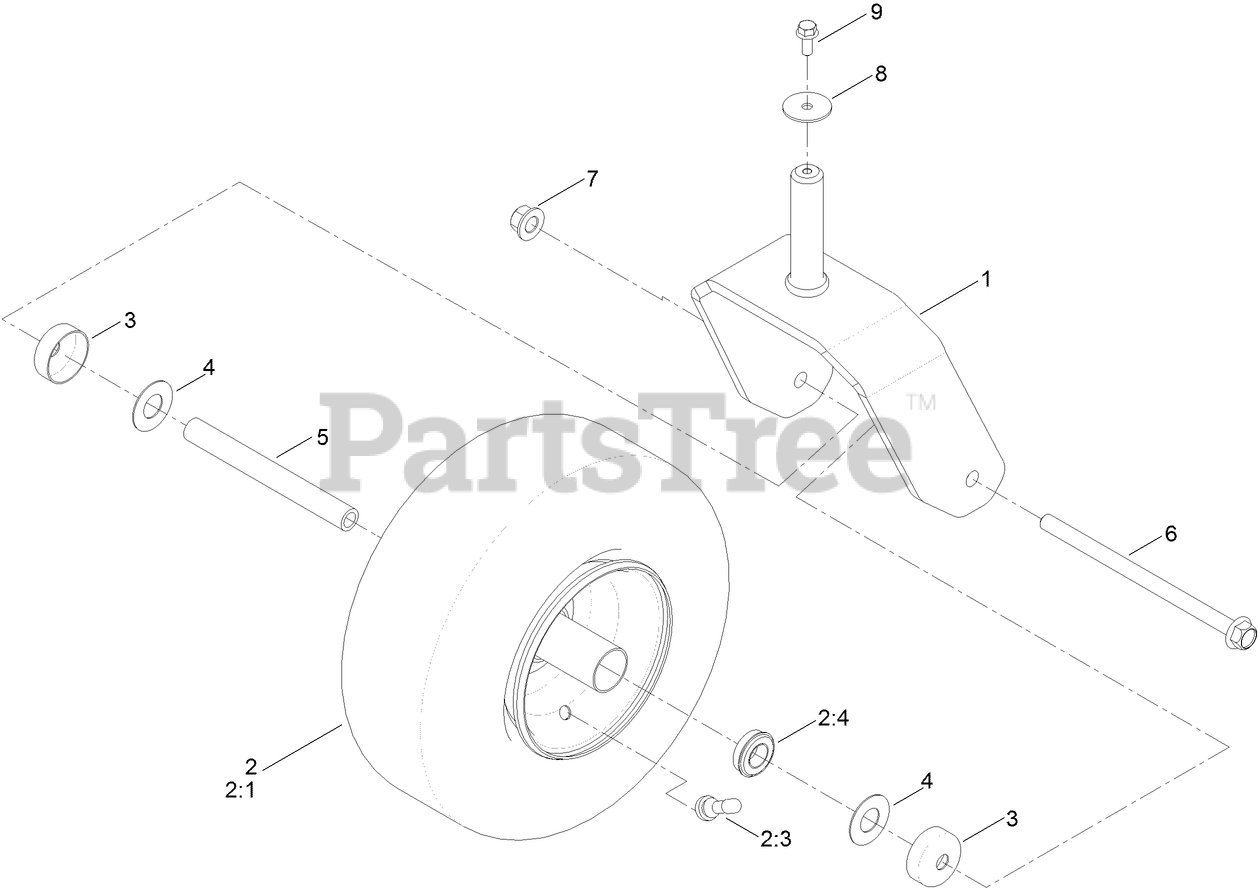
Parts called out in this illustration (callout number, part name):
1	FORK ASM
2	TIRE ASM
2:4	BEARING
3	GUARD-SEAL
4	WASHER
5	SPANNER-WHEEL
6	SCREW-HHF
7	NUT-LOCK
8	WASHER-FLAT
9	SCREW-HHF
